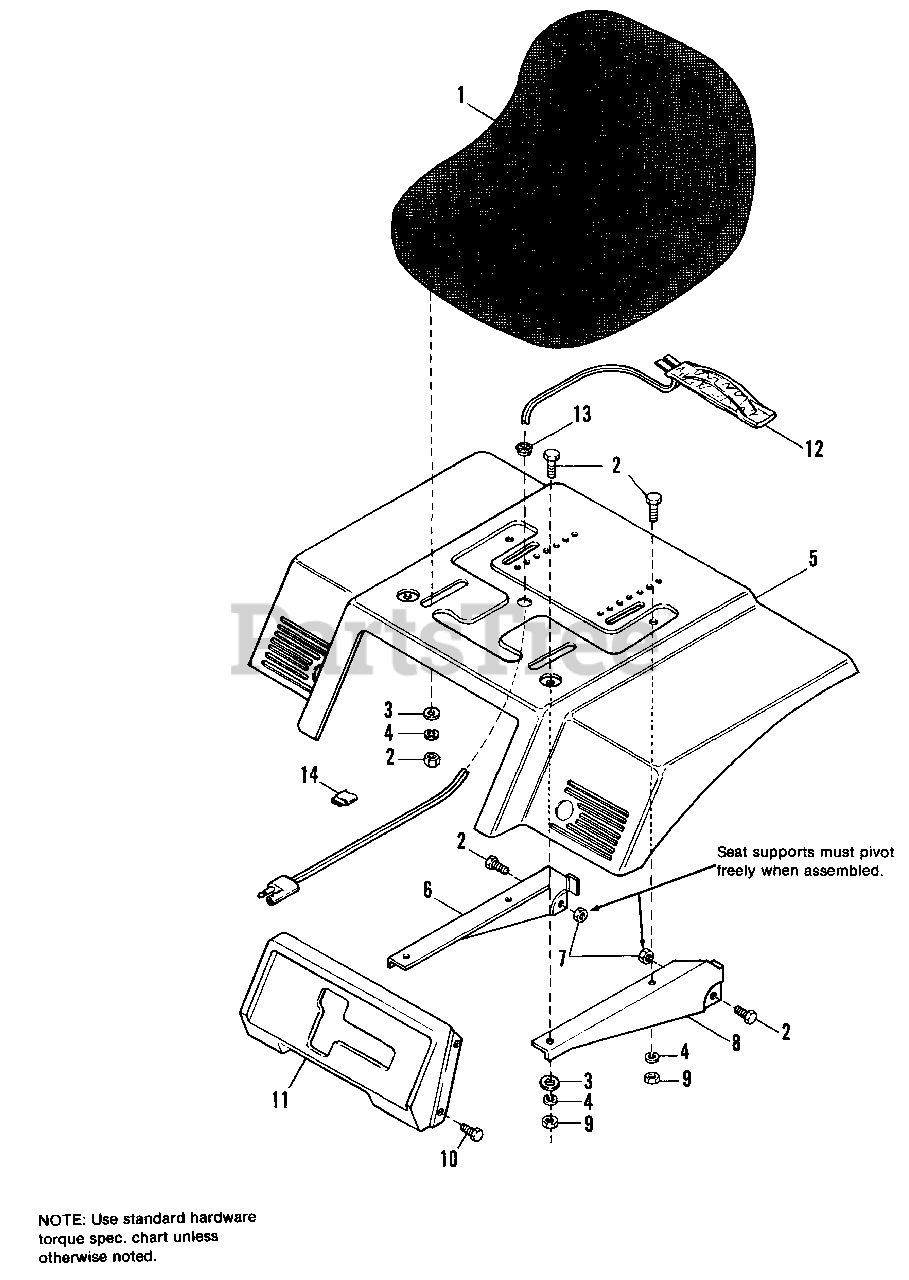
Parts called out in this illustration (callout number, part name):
2	CAPSCREW, 5/16-18 x 3/4
3	WASHER, 5/16
4	LOCKWASHER, 5/16
5	DECK, Seat
6	SUPPORT, Seat, R.H.
7	NUT, Hex, 5/16-18
8	SUPPORT, Seat, L.H.
9	NUT, Hex, 5/16-18
10	SCREW, Taptite, 1/4-20 x 1/2
11	PANEL, Shift
12	SWITCH, Seat
13	BUSHING, Universal
